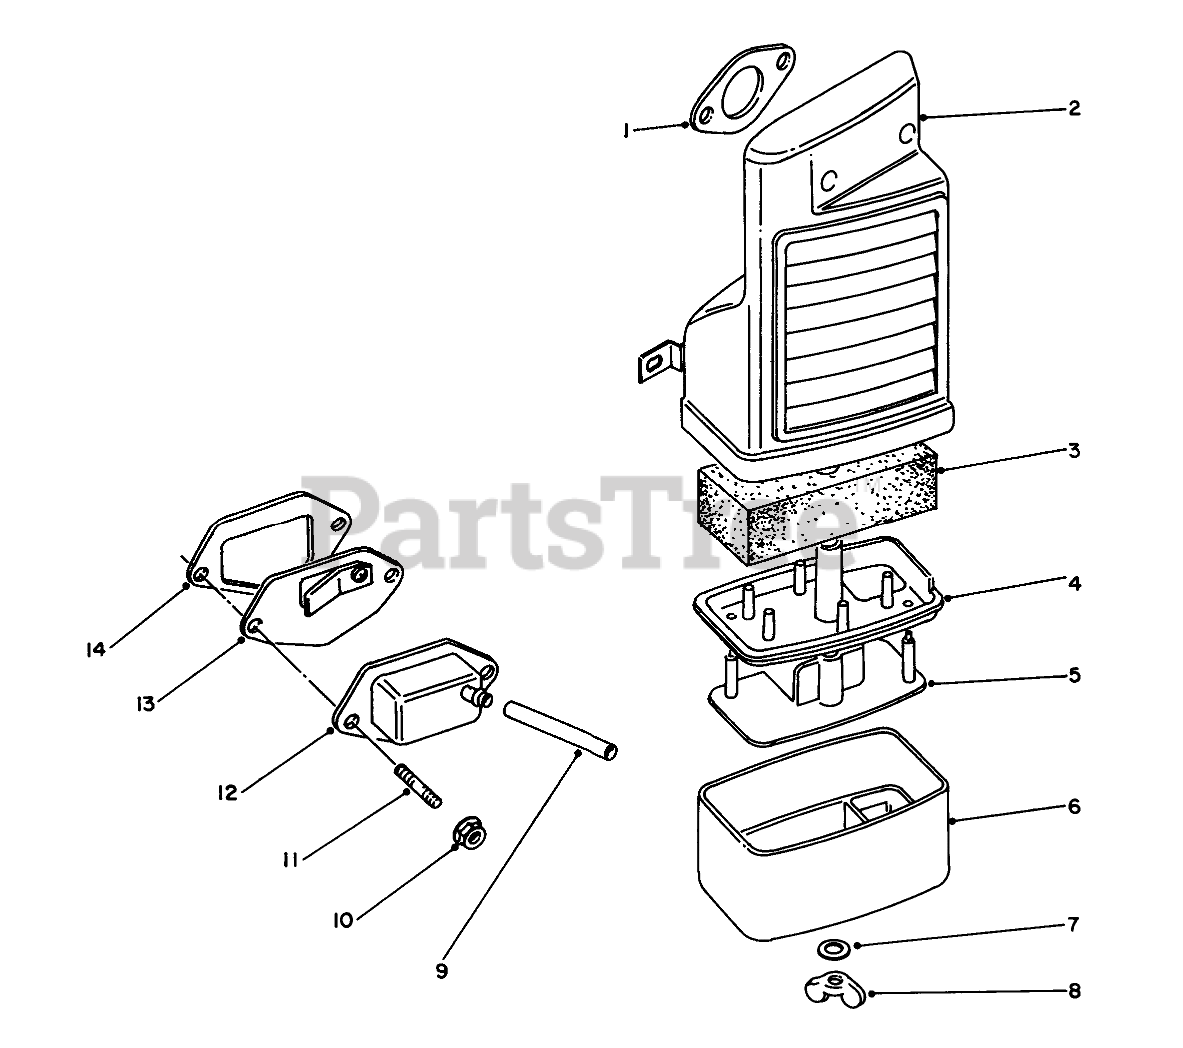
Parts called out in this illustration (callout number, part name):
1	GASKET
2	Air Cleaner Assembly (Incl. Ref. #1 & 3-8)
3	FILTER
4	Partition (B)
5	Partition (A)
7	WASHER
11	Bolt-Stud
12	Cap-Breather
13	Reed Valve Assembly
14	Gasket
